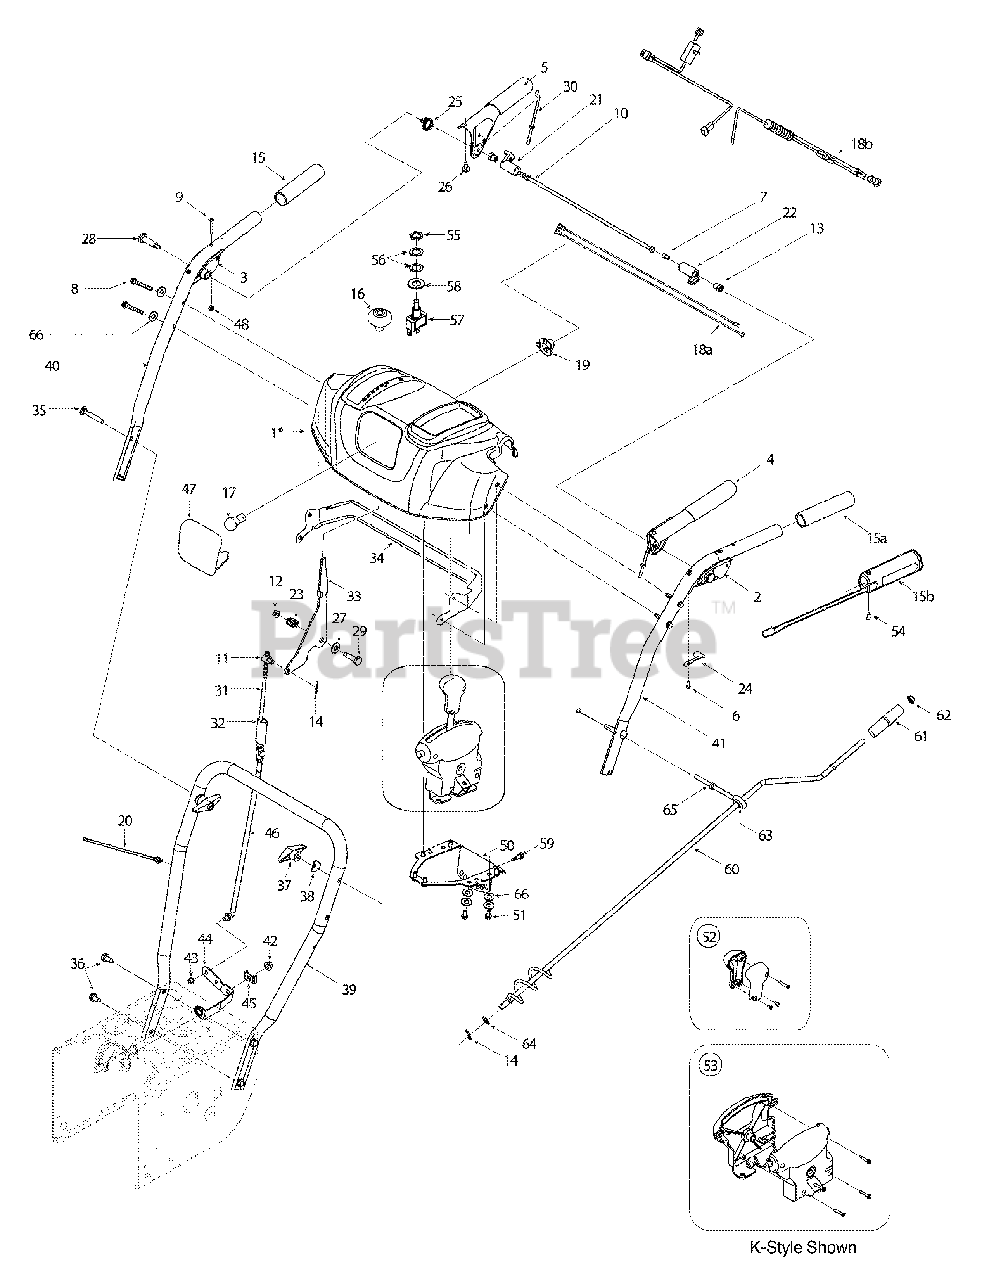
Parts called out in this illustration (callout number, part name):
1	Panel Ass'y, Handle, Black, H-Style
1	Panel Ass'y, Handle, Black, K-Style
1	Panel Ass'y, Handle, Gray, K-Style
2	Handle Assembly, Clutch Lock, LH
3	Handle Assembly, Clutch Lock, RH
4	Handle Assembly, Engagement, LH
5	Handle Assembly, Engagement, RH
6	Screw, #8-16 x.50
7	Screw, 1/4-20 x .375
8	Screw, Self-tapping, 1/4-20 x 1.750
9	Screw, Machine, #10-24 x 1.375
10	Rod, Pivot
11	Ferrule , 5/16-18 x .312
12	Nut, Flange Lock, Nylon, 1/4-20
13	Nut, Shoulder, Hex, 1/4-20,
14	Pin, Cotter,.072 Dia. x 1.13
15A	Grip, 1.0 ID x 5.0
15B	Heated Grip
16	Knob, Shift
17	Lamp
18A	Harness, w/o Heated Grips
18B	Harness, Heated Grips
19	Socket, Lamp
20	Tie, Cable , 19x 8.39", Tree Mount
21	Plate, Lock
22	Cam, Clutch Lock
23	Spring, Compression,.39 x.60 x.88
24	Spring, Clutch, Lock
25	Spring, Torsion, 0.8156 ID x.3038
26	Bumper, Rubber,.62 OD x.22
27	Washer, Flat, .385 x .870 x .092
28	Screw, Shoulder, .437 x 1.345, 1/4-20
29	Screw, Shoulder, .374 Dia. x 1.05
30	Z-Fitting, Cable
31	Rod, Shift,.312 x 9.0 Upper
32	Connector Sleeve, Shift Rod
36	Screw, 5/16-12, 0.750
37	Wing Knob, 5/16-18
38	Washer, Saddle, 320 x .93 x .060
42	Nut, Flange Lock, Nylon, 5/16-18
43	Nut, Speed,.3125 Dia.
44	Spring Lever, Shift
45	Shift Bracket Spacer
46	Shift Rod, Lower
47	Lens
48	Nut, Hex Lock, Nylon, #10-24, Gr2
51	Screw, 1/4-15x .50
52	Kit. 2-Way Knob
53	Kit, Chute Control Housing
53	Joystick Control Assembly Complete
54	Screw, #10-16 x.625
55	Jam Nut, 15/32-32
56	Toggle Switch Lock Ring
57	2 Pos., Single Throw Toggle Switch
58	Flat Washer,.474 x.879 x.064
59	Shoulder Screw,.25 x.50
61	Chute Directional Control Knob
62	Push Cap
63	Rubber Grommet
64	Flat Washer,.375 x .738 x .063
65	Eye Bolt
66	Washer, Flat, .25 x .630 x.0515
